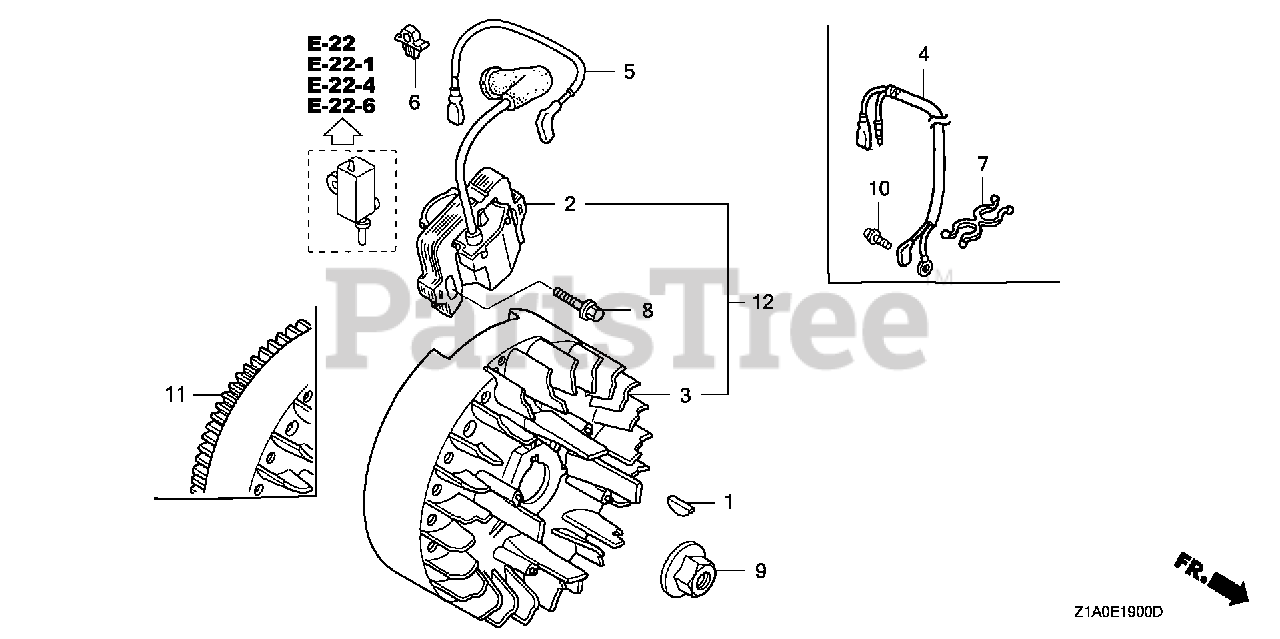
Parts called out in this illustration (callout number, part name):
1	KEY, SPECIAL WOODRUFF (25X18)
2	COIL ASSY., IGNITION (PHELON) (USE FOR F/W OF PHELON)
2	COIL ASSY., IGNITION (PHELON)
3	FLYWHEEL COMP. (PHELON) (USE FOR IGN. COIL OF PHELON) (USE FOR PHELON IGNITION COIL)
5	WIRE, STOP SWITCH
6	HOLDER, STOP SWITCH WIRE Use up to Engine SN 2056819.
8	BOLT, FLANGE (6X20) (CT200)
9	NUT, FLANGE (14MM)
